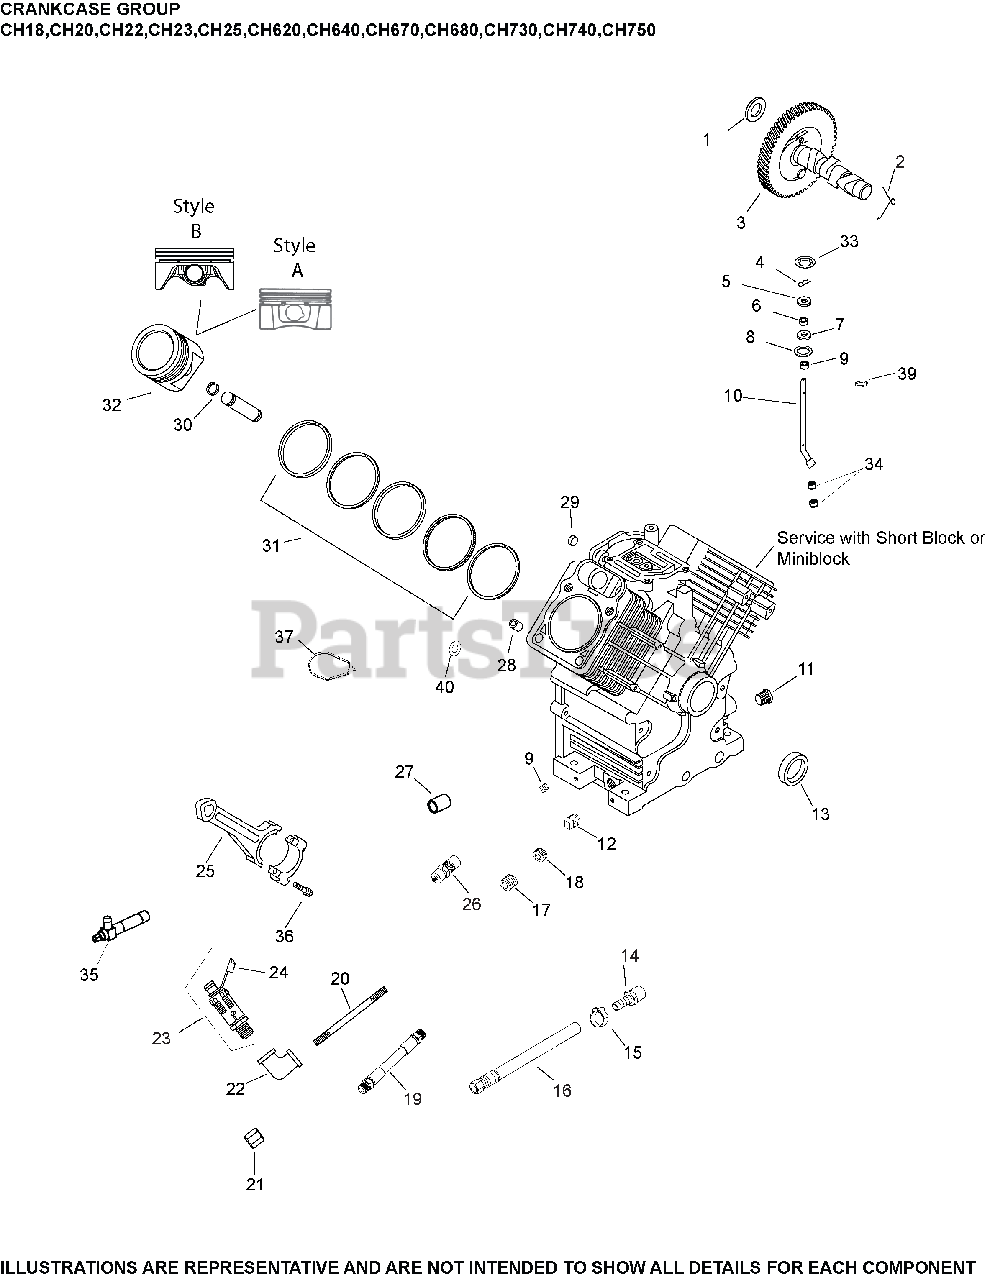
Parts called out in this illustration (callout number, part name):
3	KIT, CAMSHAFT
5	WASHER, FLAT 9 MM
7	SEAL, GOVERNOR CROSS SHAFT
8	WASHER, FLAT 11/32"
10	SHAFT, GOVERNOR CROSS
12	PLUG, SQ HD PIPE 3/8"
13	SEAL, OIL (HELIX LIP)
25	KIT, CONNECTING ROD ASSEMBLY USE 25 067 04-S
28	PIN, LOCATING
29	PLUG, CUP
30	RETAINER, PISTON PIN
31	RING SET (STD)1.5MM TOP RING THICKNESS (STYLE A)
31	RING SET (.08)1.5MM TOP RING THICKNESS - DISCONTINUED (STYLE A)
31	RING SET (.25)1.5MM TOP RING THICKNESS - DISCONTINUED, USE PISTON ASSEMBLY (STYLE A)
31	RING SET (.50)1.5MM TOP RING THICKNESS (STYLE A)
32	PISTON W/RINGS (STYLE A)(STD) - RING SET 24 108 22-S
32	PISTON W/RINGS (STYLE A)(.08) - RING SET 24 108 23-S - DISCONTINUED
32	PISTON W/RINGS (STYLE A)(.25) - RING SET 24 108 24-S
32	PISTON W/RINGS (STYLE A)(.50) - RING SET 24 108 25-S
33	RETAINER, RING
36	KIT, ROD BOLTS
